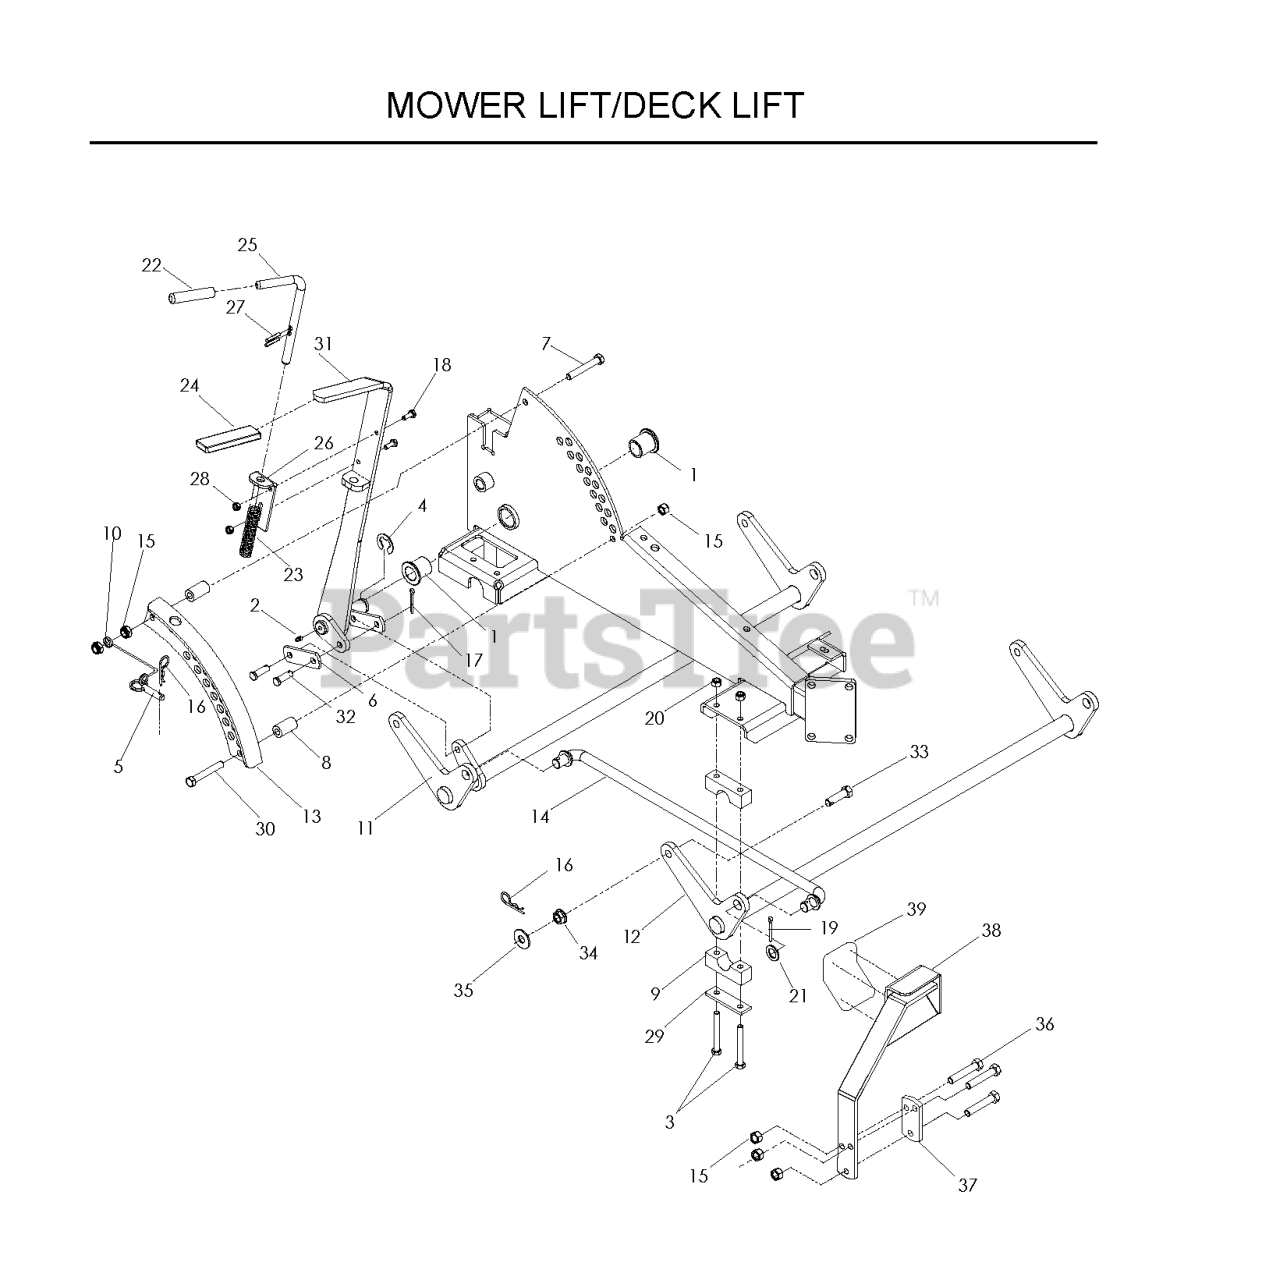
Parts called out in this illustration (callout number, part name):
1	BUSHING, FLANGED
3	HCS 5/16C X 2-3/4
4	E-RING 7/8
7	SCREW 3/8C X 2 3/4 HEX CAP
8	DECK LIFT SPACER
9	PILLOW BLOCK
11	REAR LIFT SHAFT
12	FRONT LIFT SHAFT
13	ADJUSTMENT PLATE WLDMT
14	CROSS LINK
15	NUT 3/8-16 NYLOC
16	HAIRPIN #4
17	RP_COTTER PIN 1/8 X 3/4
18	HCS 1/4C X 3/4 HCS
19	COTTER PIN
20	NUT 5/16 NYLOC
26	PIN MT, UPPER
28	NUT 1/4C CENTER LOCK
29	REINFORCEMENT BAR
30	HCS 3/8C X 2 1/2
31	LIFT LEVER WELDMENT
32	CLEVIS PIN 3/8 X 1 1/8
33	HCS 7/16-14X1-1/2 GR5 ZD SPEC
34	NUT 7/16C WHIZ
35	WASHER 7/16 FLAT ZD
36	HCS 3/8C X 1 1/2
37	TIGHTENING PLATE BLK
38	LIFT PEDAL BLK
39	ANTI-SKID PAD
